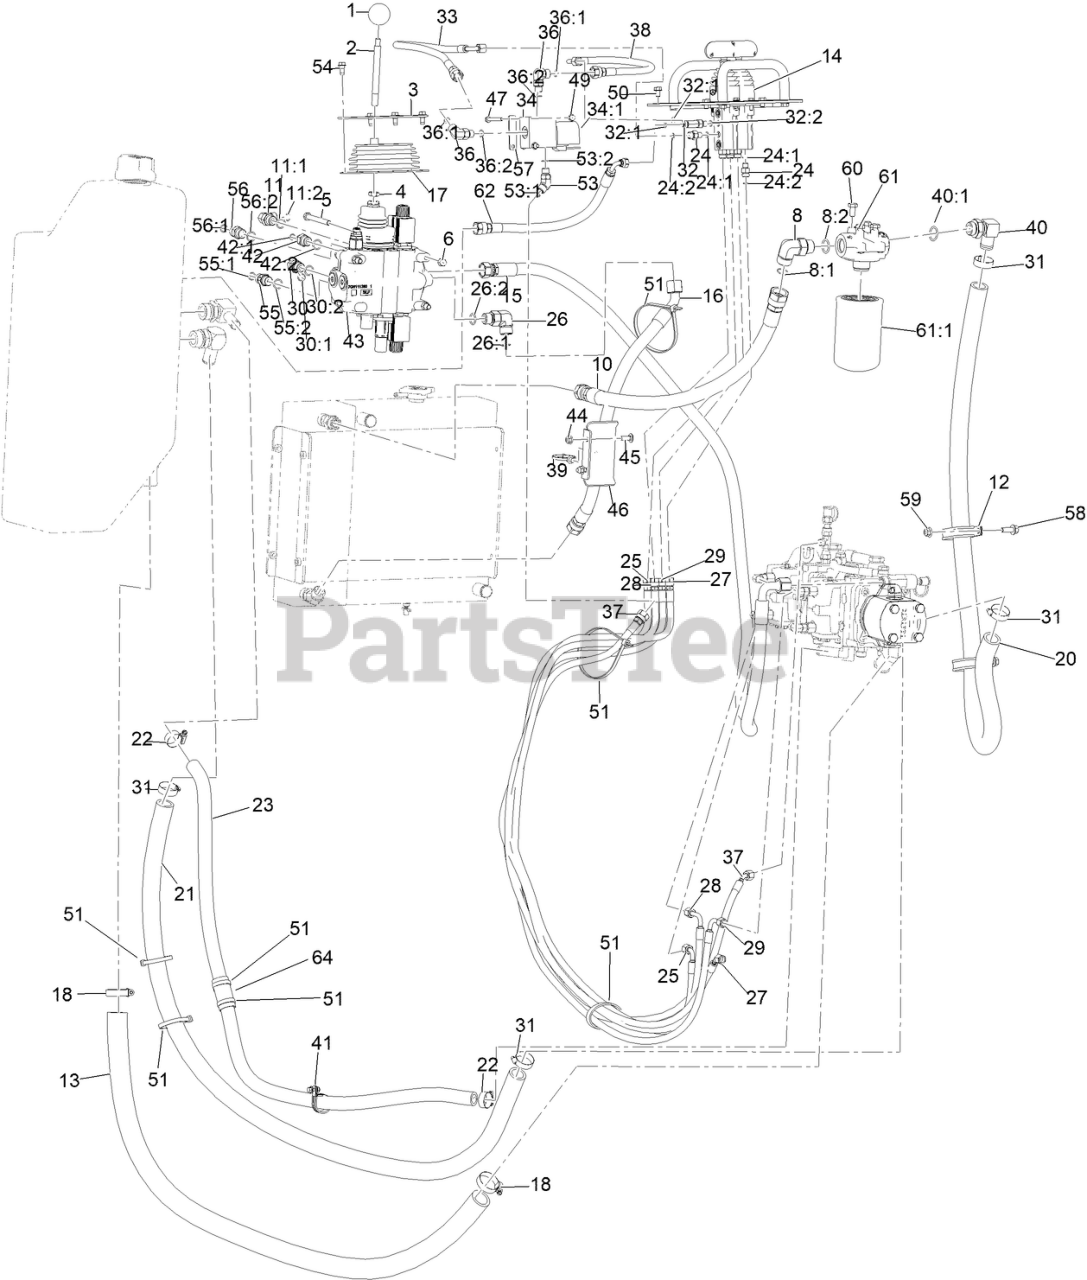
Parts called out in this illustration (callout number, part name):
2	SHAFT-HANDLE, LOADER
3	RING-BOOT
5	SCREW-HH
6	NUT-LOCK, NI
8	FITTING-ELBOW-90
8:1	O-RING
8:2	O-RING
10	HOSE ASM-HYD
11	FITTING-ELBOW, 90 DEG
11:1	O-RING
11:2	O-RING
12	CLAMP-R, DOUBLE
13	HOSE-RETURN
14	TRACTION CONTROL ASM
15	HOSE-HYD ASM
16	HOSE ASM-HYD
17	BOOT-CONTROL
20	HOSE-RETURN
21	HOSE-RETURN
22	CLAMP-HOSE
23	HOSE-RETURN
24	FITTING-STRAIGHT
24:1	O-RING
24:2	O-RING
25	HOSE ASM-HYD
26	FITTING-ELBOW, 90 DEG
26:1	O-RING
26:2	O-RING
27	HOSE ASM-HYD
28	HOSE ASM-HYD
29	HOSE ASM-HYD
30	FITTING-HYD, 45 DEG
30:1	O-RING
30:2	O-RING
31	CLAMP-HOSE
32	FITTING-TEE
32:1	O-RING
32:2	O-RING
33	HOSE ASM-HYD
34	SOLENOID VALVE
34:1	SOLENOID COIL
36	FITTING-ELBOW, 90 DEG
36:1	O-RING
36:2	O-RING
37	HOSE ASM-HYD
38	HOSE ASM-HYD
39	CLIP-TIE
40	FITTING-90
40:1	O-RING
41	CLAMP-R
42	FITTING-STRAIGHT
42:1	O-RING
42:2	O-RING
43	LOADER VALVE ASM,
44	NUT-HF, NI
45	BOLT-CARR
46	PLATE-HOSE
47	SCREW-HH
49	NUT-HF
50	SCREW-HHF
51	TIE-CABLE
53	FITTING-ELBOW, 45 DEG
53:1	O-RING
53:2	O-RING
54	SCREW-SHOULDER
55	VALVE-CHECK
55:1	O-RING
55:2	O-RING
56	FITTING-STRAIGHT
56:1	O-RING
56:2	O-RING
57	PLATE, BACKING
58	SCREW-HHF
59	NUT-HF, NI
60	SCREW-HH
61	FILTER-OIL
61:1	FILTER-HYD
62	HOSE ASM-HYD
64	PROTECTOR-HOSE
